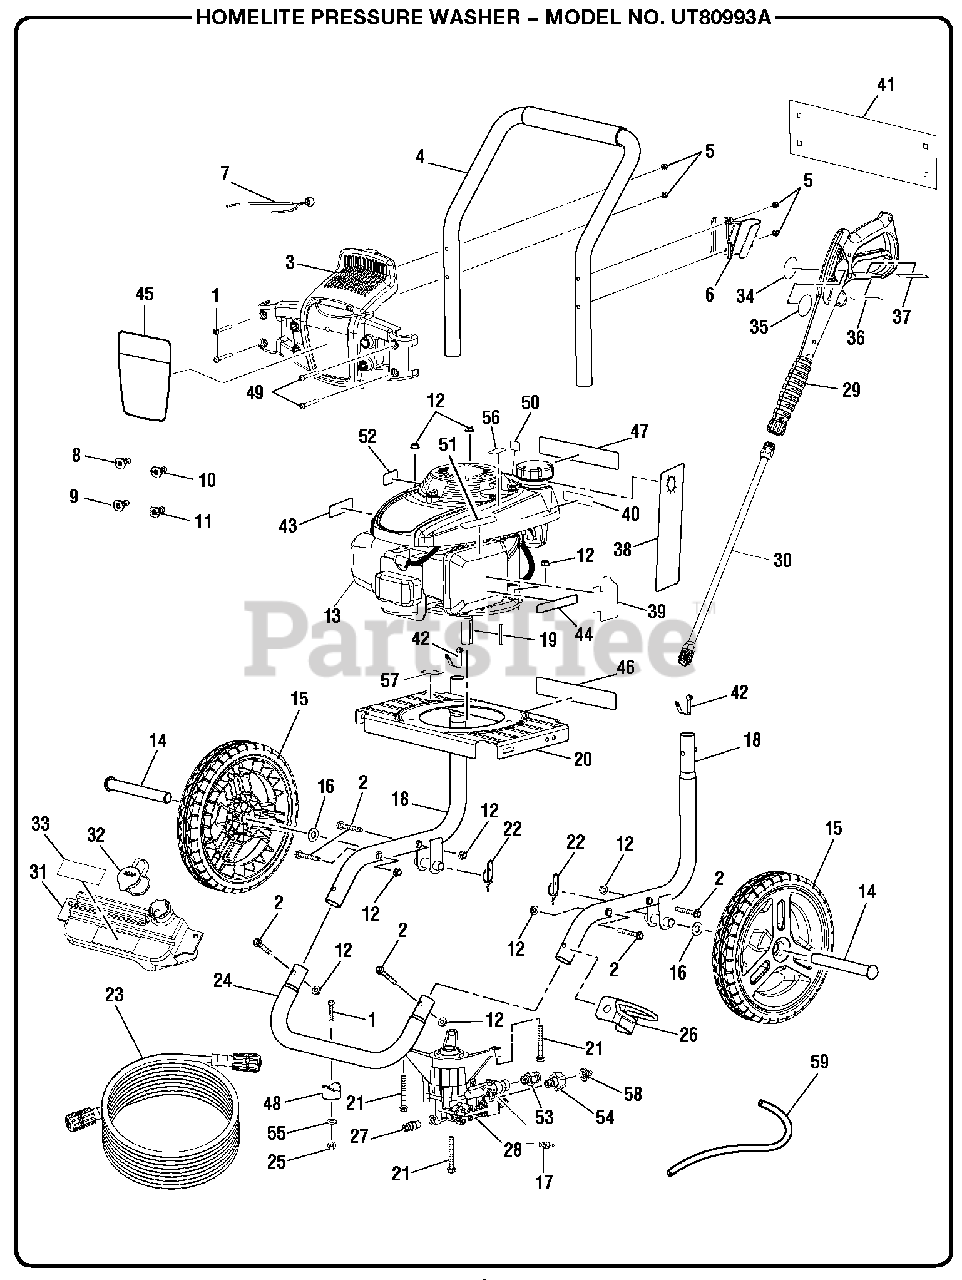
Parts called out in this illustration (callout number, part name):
1	Screw (1/4-20 x 1.85 in., T30 Torx Hd.)
2	Bolt (M8 x 55 mm)
3	Hose and Nozzle Holder Assembly
4	Handle w/Foam
5	Lock Nut (1/4-20)
6	Wand Holder
7	Bungee Cord Assembly
8	40deg Nozzle
9	Soap Nozzle
10	25deg Nozzle
11	0deg Nozzle
12	Flange Nut (M8 x 1.25)
13	Engine (Honda GCV 160, 161cc OHC Vertical)
16	Washer (1/2 in.)
17	Detergent Suction Kit
18	Main Frame Assembly
19	Output Shaft Key (40 mm)
20	Engine Plate
21	Bolt (M8 x 60 mm, Flange Hd.)
22	Axle Clip
23	Hose (25 ft., 3100 psi)
24	Front Frame
25	Lock Nut (1/4-20)
26	Wand Holder Loop
27	Thermal Release Valve
28	Pump
29	Trigger Handle Assembly
30	Extension Wand
31	Soap Tank
32	Soap Tank Cap
33	Soap Dilution Label
34	Label (Wand Logo)
35	Label (Wand Warning)
36	Fr/Sp Label (Wand Warning)
37	Label (Wand Rating)
38	Danger Hangtag
39	Engine Control Label
40	Combustion Label
41	Quick Start Panel
42	Lock Button w/Spring Clip
43	Hot Surface Label
44	EMC Label
45	Performance Label
46	Data Label
47	Danger Label
49	Screw (1/4-20 x 2 in., T30 Torx Hd.)
50	No E85 Label
51	Inquiries Label
52	Lubricant Label
53	Outlet Tube
54	Inlet Tube
55	Washer (1/4 in.)
56	Release Water Label
57	Oil Fill Location Label
58	Filter Screen (Pump Inlet)
59	Chemical Siphon Tube
